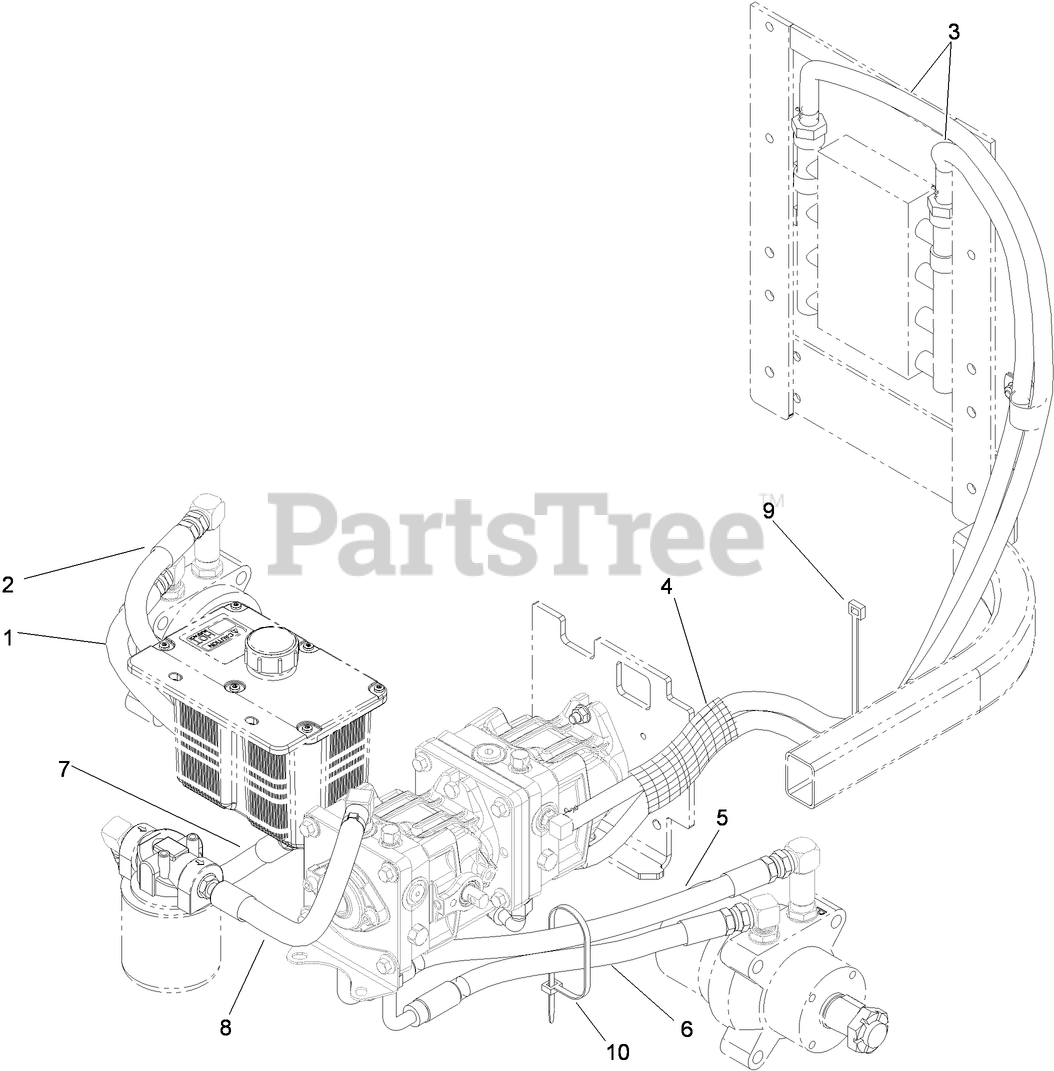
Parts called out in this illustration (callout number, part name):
1	HYDRAULIC HOSE ASM
2	HYDRAULIC HOSE ASM
3	HOSE-HYDRAULIC
4	SLEEVE-FABRIC
5	HYDRAULIC HOSE ASM
6	HYDRAULIC HOSE ASM
7	HYDRAULIC HOSE ASM
8	HYDRAULIC HOSE ASM
9	TIE-PLASTIC
10	CABLE TIE-PLASTIC
